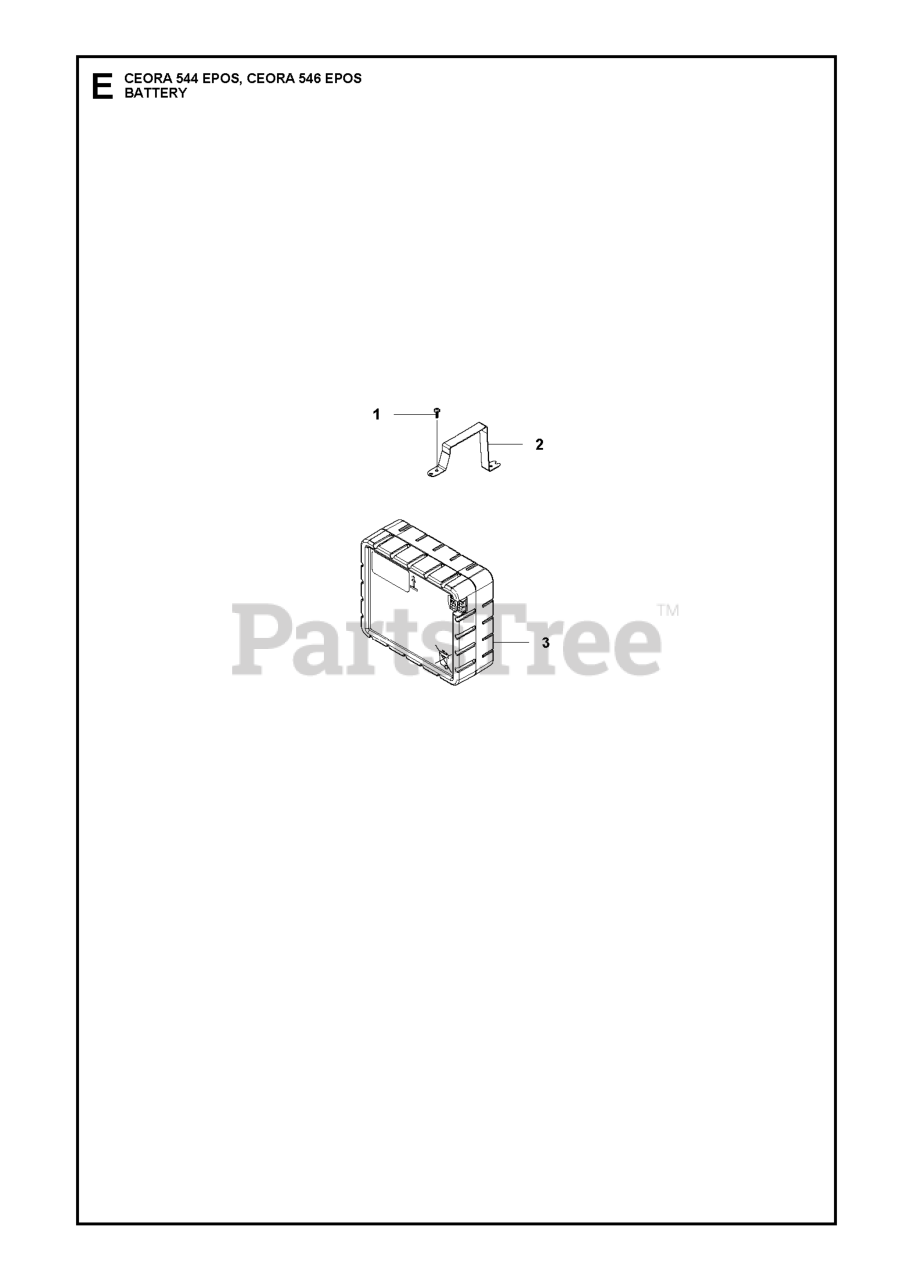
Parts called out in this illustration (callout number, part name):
1	SCREW ITXPANT
2	HOLDER BATTERY
3	BATTERY PREMIUM 10S10P TYPE 31
